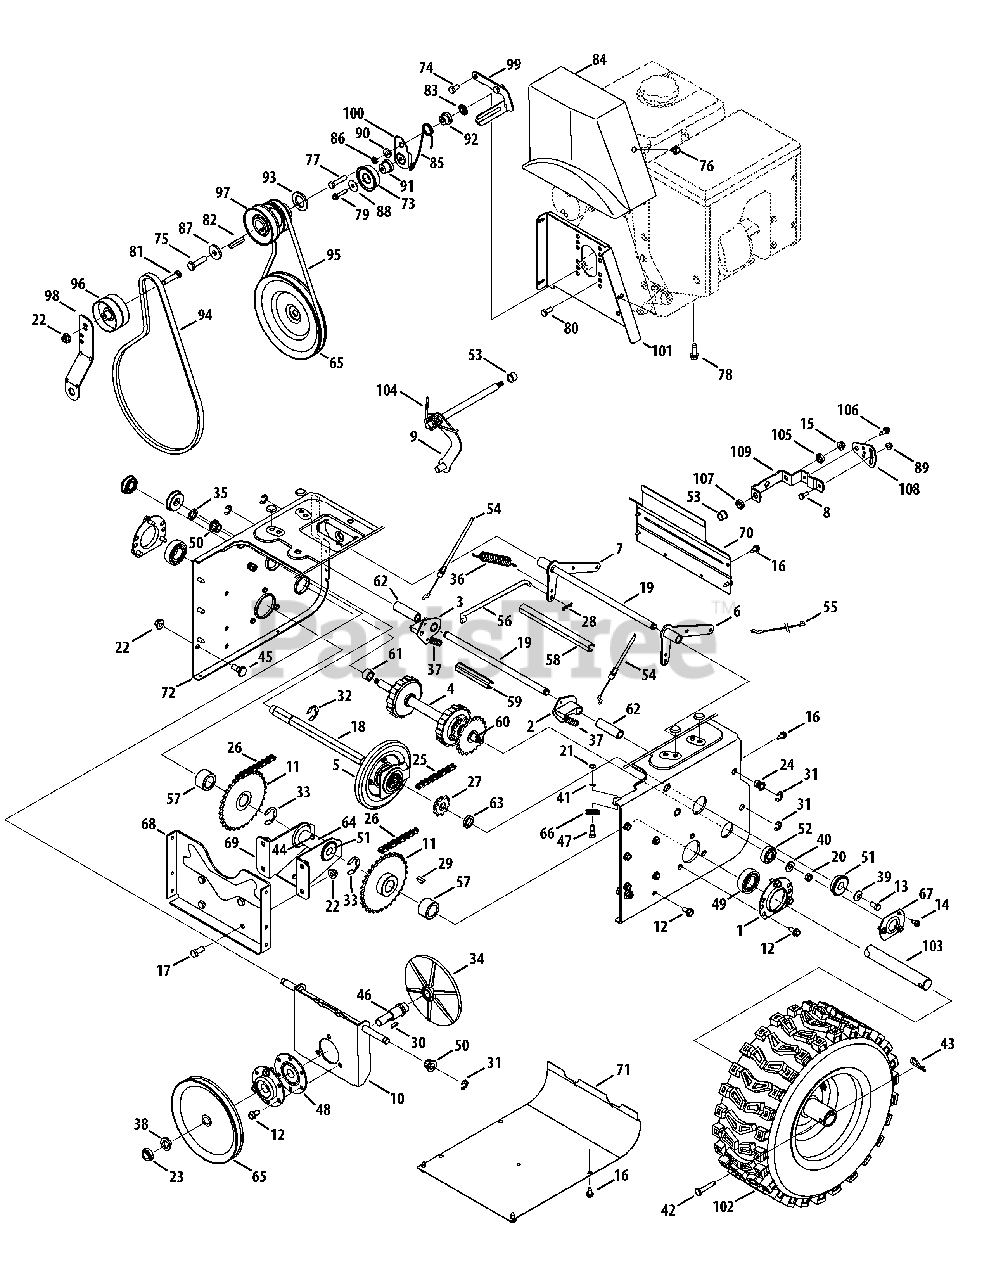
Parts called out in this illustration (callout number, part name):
1	Housing, Bearing
2	Dogg, Steering Drive, LH
3	Dogg, Steering Drive, RH
4	Shaft Assembly, Steering
5	Assembly, Friction Wheel
5	Wheel, Friction, Bonded
5	Screw, Hex Wash
6	Bracket, Auger Actuator
7	Bracket, Drive Actuator
8	Hex Head Screw, 1/4-20
9	Rod Assembly, Shift
10	Brkt, Friction Drive Suprt.
11	Sprocket, 32T
12	TT Screw, 5/16-18 x .750
13	Screw, Hex Cap Lock,
14	Screw, Hex, 1/4-20 x .50
15	Flange Lock Nut 5/16-18
16	Screw, Hex Wash.
17	Screw, Hex Cap, 3/8-16
18	Shaft, Hex Drive
19	Shaft, Actuator
20	Nut, Hex Insert Jam Lock
21	Nut, Hex, 1/4-28 GR5
22	Nut, Hx Flnge Insert Lk
23	Nut, Hx Insert Jam Lk
24	Nut, Insert 3/8-16
25	Chain, Endless, #41 x 36L
26	Chain, #420 x 40L
27	Sprocket, #41 x 10T
28	Pin, Internal Cotter
29	Key, Woodruff
30	Key, Hi-Pro, 3/16 x 5/8
32	Ring, Retaining
33	Ring, Retainer
34	Plate, Drive
35	Speed Nut, .500
36	Spring, Extension
37	Spring, Extension
38	Washer, Lock, 5/8
39	Wsh, Bell., .34 x .872 x .06
40	Wash, .375 x .812 x .060
41	Washer, Lock, 1/4
42	Pin, Clevis
43	Pin, Internal Cotter
44	Fitting, Lube, 3/16 Drive
45	Screw, Shldr., .498 x .34
46	Spindle, Drive Plate
47	Screw, Hex Shldr., 1/4-28
48	Ass’y, Bearing/Housing
49	Bearing, Self Aligning
50	Bearing, Hex Flange
51	Bearing, Ball
52	Bush, Flg, .5625 ID x 1.375 x .4375
53	Bush, Flg, .5 ID x .627 OD
54	Cable, Steering
55	Cable, Auger Idler
56	Rod, Drive Clutch
57	Spacer, 1.01 x 1.50 x .93
58	Spacer, .49 x 7.865
59	Spacer, .49 x 3.545
60	Spacer, .566 x .87 x .190
61	Spacer, .566 x .87 x 1.25
62	Spcr., .514 x .632 x 2.44
63	Spacer, .675 x 1.0 x .23
64	Spcr, .6725 x 1.125 x 2.48
65	Pulley, Drive
66	Roller, Cable
67	Retainer Bracket
68	Bracket, Frame Support
69	Bracket, Axle Support
70	Cover, Upper Frame
71	Cover, Lower Frame
72	Trans Frame
73	Idler Pulley Assembly
74	Screw, Hex 5/16-24 x .75
75	Screw, Hex 3/8-24 x 1.25
76	Screw, Hx Wash Hd Tapp
77	Screw, Hex Cap, 5/16-24 x 1.50
78	Screw, 3/8-16 x 1.00
79	Screw, 1/4-20 x 1.25
80	Screw, Shldr., .500 x .145
81	Screw, Hex Cap, 3/8-16 x 1.75
82	Key, Square, 1/4 x 1.5
83	Nut, Push
84	Cover, Belt
85	Torsion Spring, .850 dia. x .333 lg.
86	Washer, Lock, 5/16
87	Washer, Flat, .406 x 1.25
88	Washer, Flat, .265 x 1.0 x .030
89	Flange Lock Nut 1/4-20
90	Shldr. Spacer, .3175 x .500 x .094
91	Shldr. Spacer, .260 x .785 x .538
92	Shoulder Spacer, .340 x 1.00
93	Spacer, 1.02 x 1.63 x .1425
94	V-Belt, 4L x 44.60
95	V Belt, 3/8 x 36.68
96	Pulley, Flat Idler, 2.75 OD
97	Double Pulley, 3.25 x 2.75
98	Bracket, Auger Idler
99	Belt Keeper Bracket
100	Idler Drive Wheel Bracket
101	Belt Cover Bracket
102	Wheel Ass’y. - LH
102	Wheel Ass’y. - RH
103	Axle, Wheel, 45"
104	Torsion Spring, .750 I.D. x .968 Lg.
105	Flat Washer, .469 x .875 x .105
106	Shoulder Screw, .368 x .113
107	Spacer, .515 ID x .750 OD x .220
108	Speed Selector Pivot Bracket
109	Speed Selector Shift Bracket
